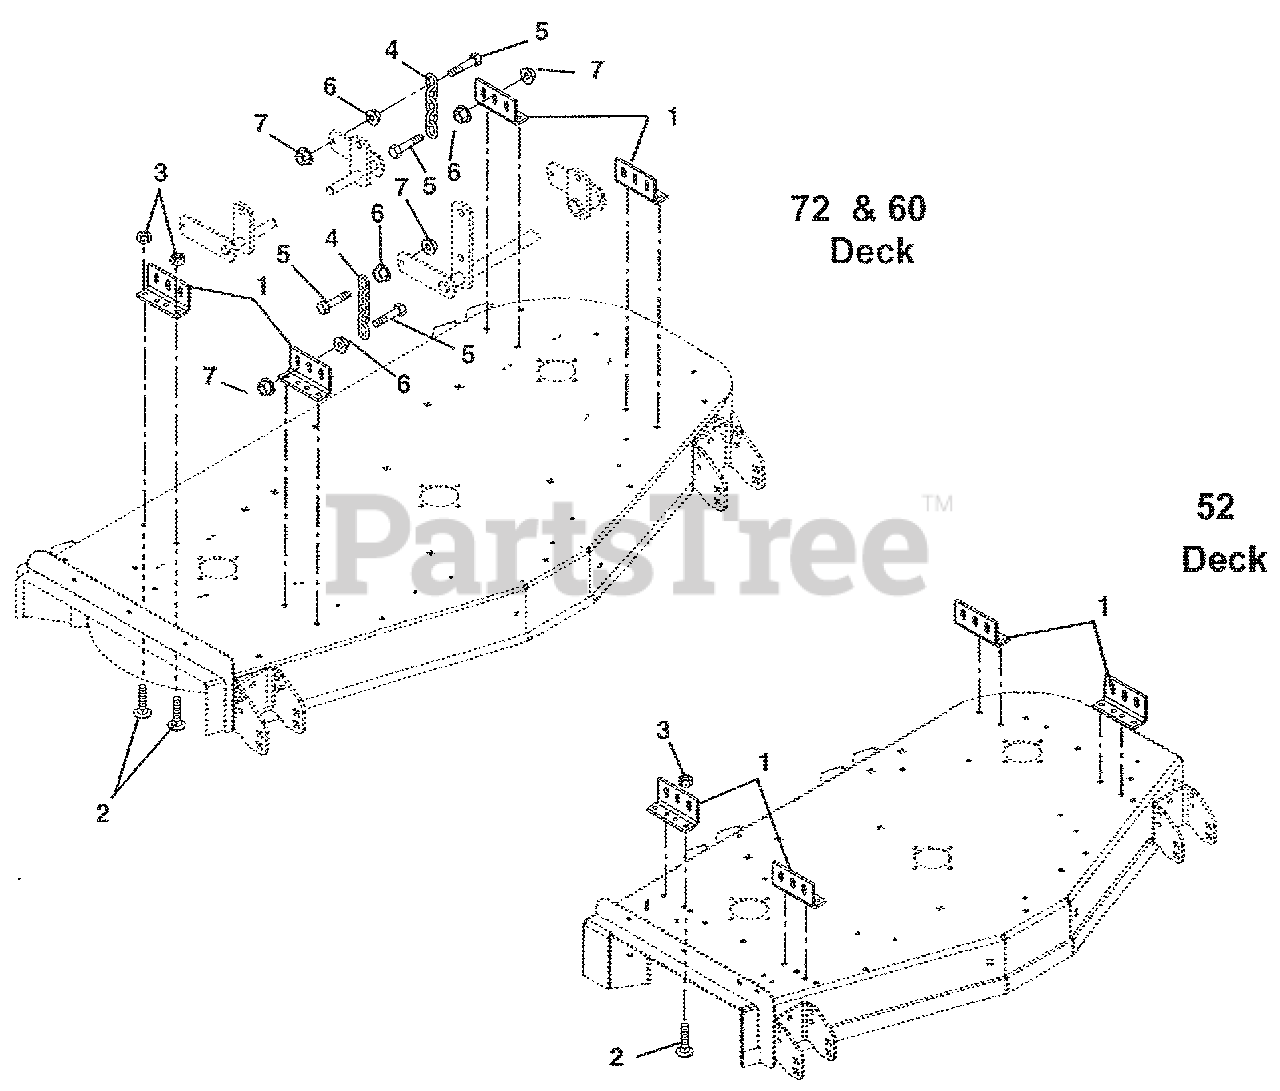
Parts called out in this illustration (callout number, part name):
1	Bracket, Mower Mounting
2	Bolt-Round Head Square Neck .38-16 1.00 Grade 2
3	Nut-Locking-Top-Flange .38-16
4	Chain, Link
5	Bolt-Hex .50-13 x 2.00 Grade 5
6	Nut, Spin Lock Flange .5-13
7	Nut-Locking-Top-Flange .50-13
